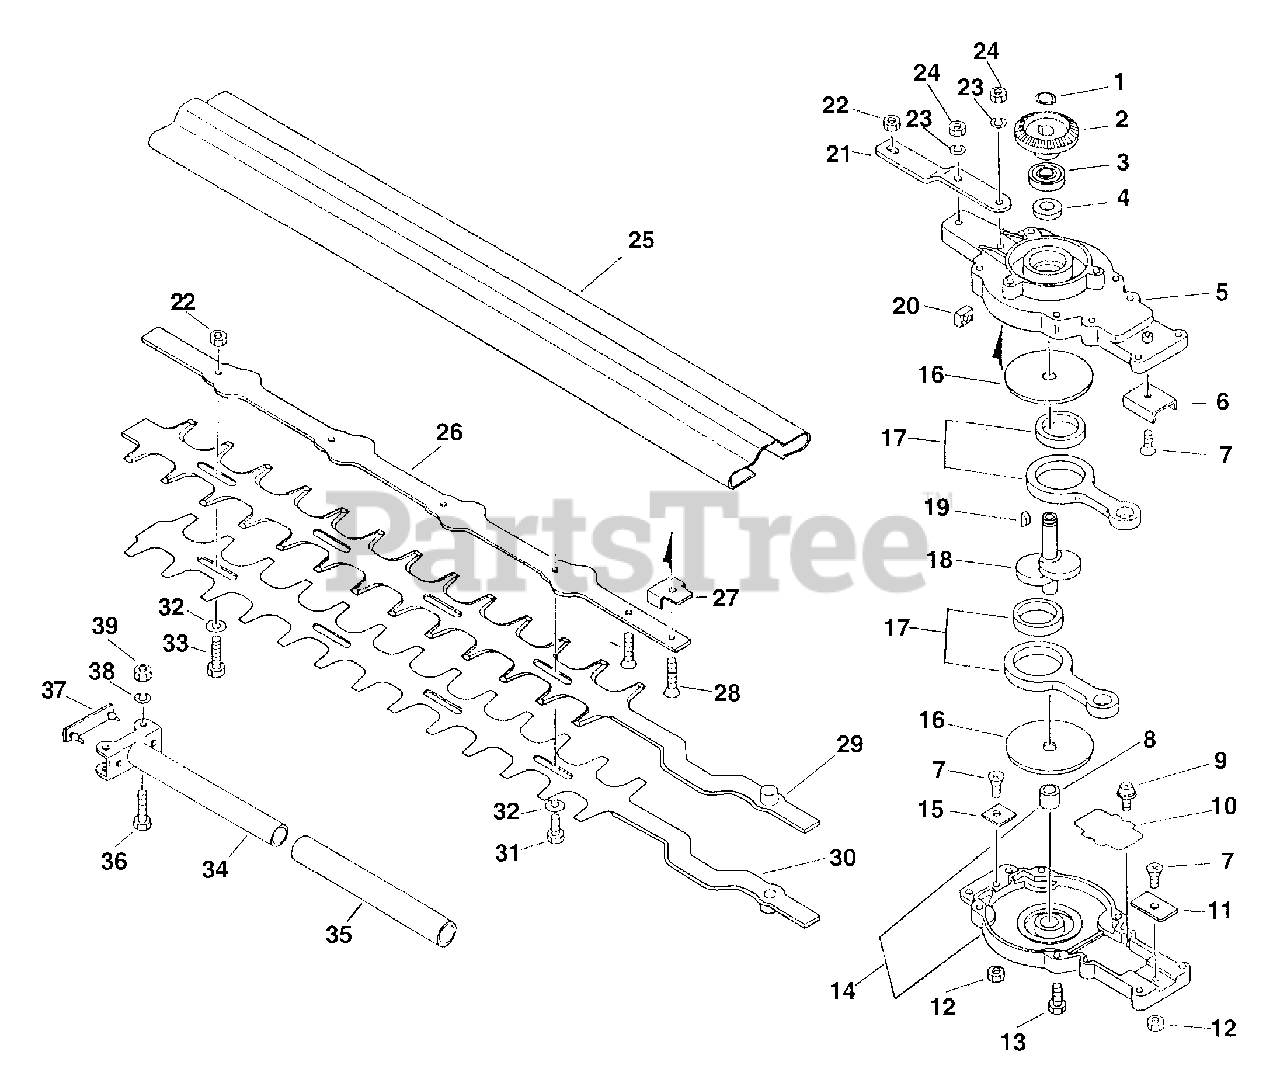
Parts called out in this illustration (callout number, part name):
1	E-RING 10
2	GEAR, SPUR
3	BEARING, BALL 6000
4	SEAL, OIL
5	CASE, GEAR
7	SCREW 4×8
8	BEARING, PLAIN
9	SCREW 3×6
10	PLATE, SIDE
11	PLATE, EYE
13	BOLT 5×20
14	GEAR CASE LID ASSY
15	PLATE, GUIDE
16	PLATE, SIDE
17	CONROD ASSY
21	SUPPORT, BLADE
23	WASHER, SPRING 5
24	NUT M5
25	SCABBARD
26	SUPPORT, BLADE
27	PLATE, ANGLE
28	SCREW 5×20
29	BLADE - UPPER -- "TB"- TOP BLADE
30	BLADE, TRIMMER - "BB"- BOTTOM BLADE
31	BOLT, CUTTER
32	WASHER 6.5×15.5×0.6
33	BOLT, CUTTER
34	ADJUSTOR ASSY, HANDLE
35	GRIP, HANDLE
36	BOLT - 5×25
37	SEAL, FELT
38	WASHER, SPRING 5
39	NUT M5
